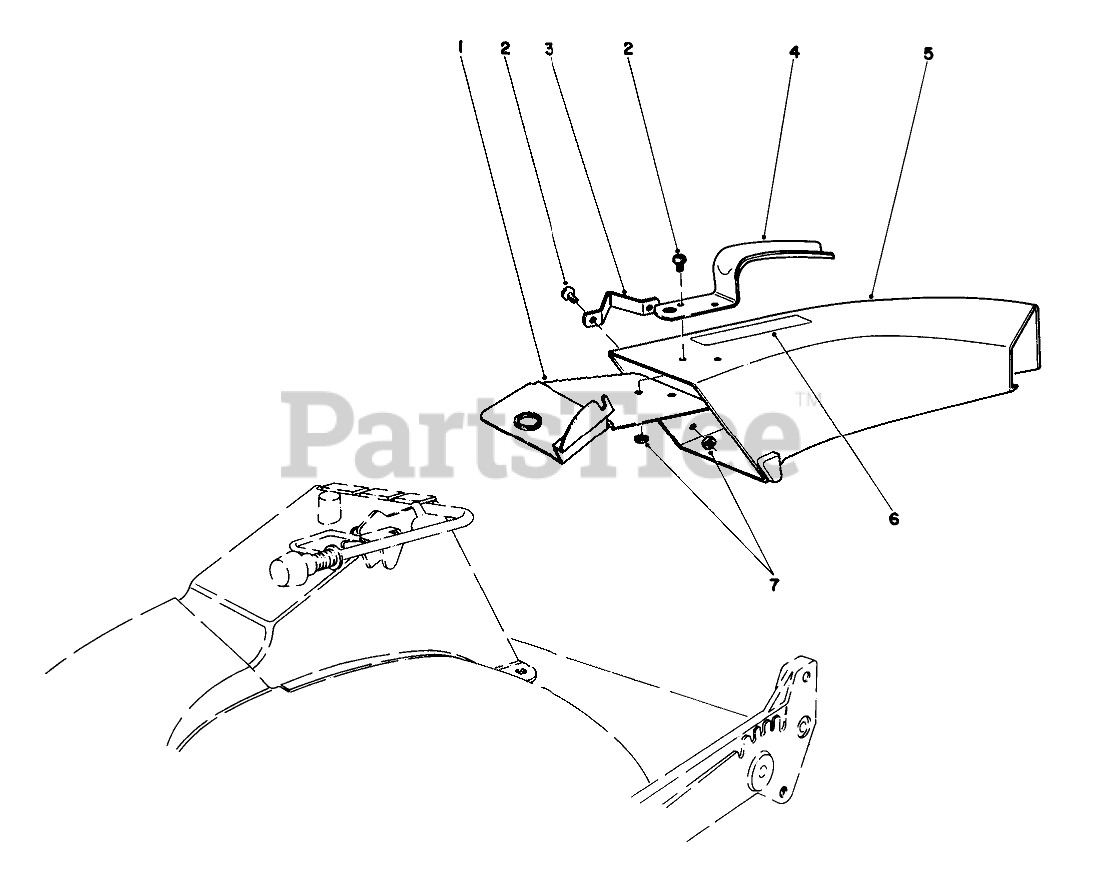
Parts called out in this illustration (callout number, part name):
1	Plate-Discharge Chut
2	10-24 X 5/8 PAN HD MS
3	SIDE BRACKET
4	CHUTE HANDLE
5	Chute Assembly (Incl. Ref. #1-6)
6	DECAL CAUTION
7	NUT-LOCK, NI
